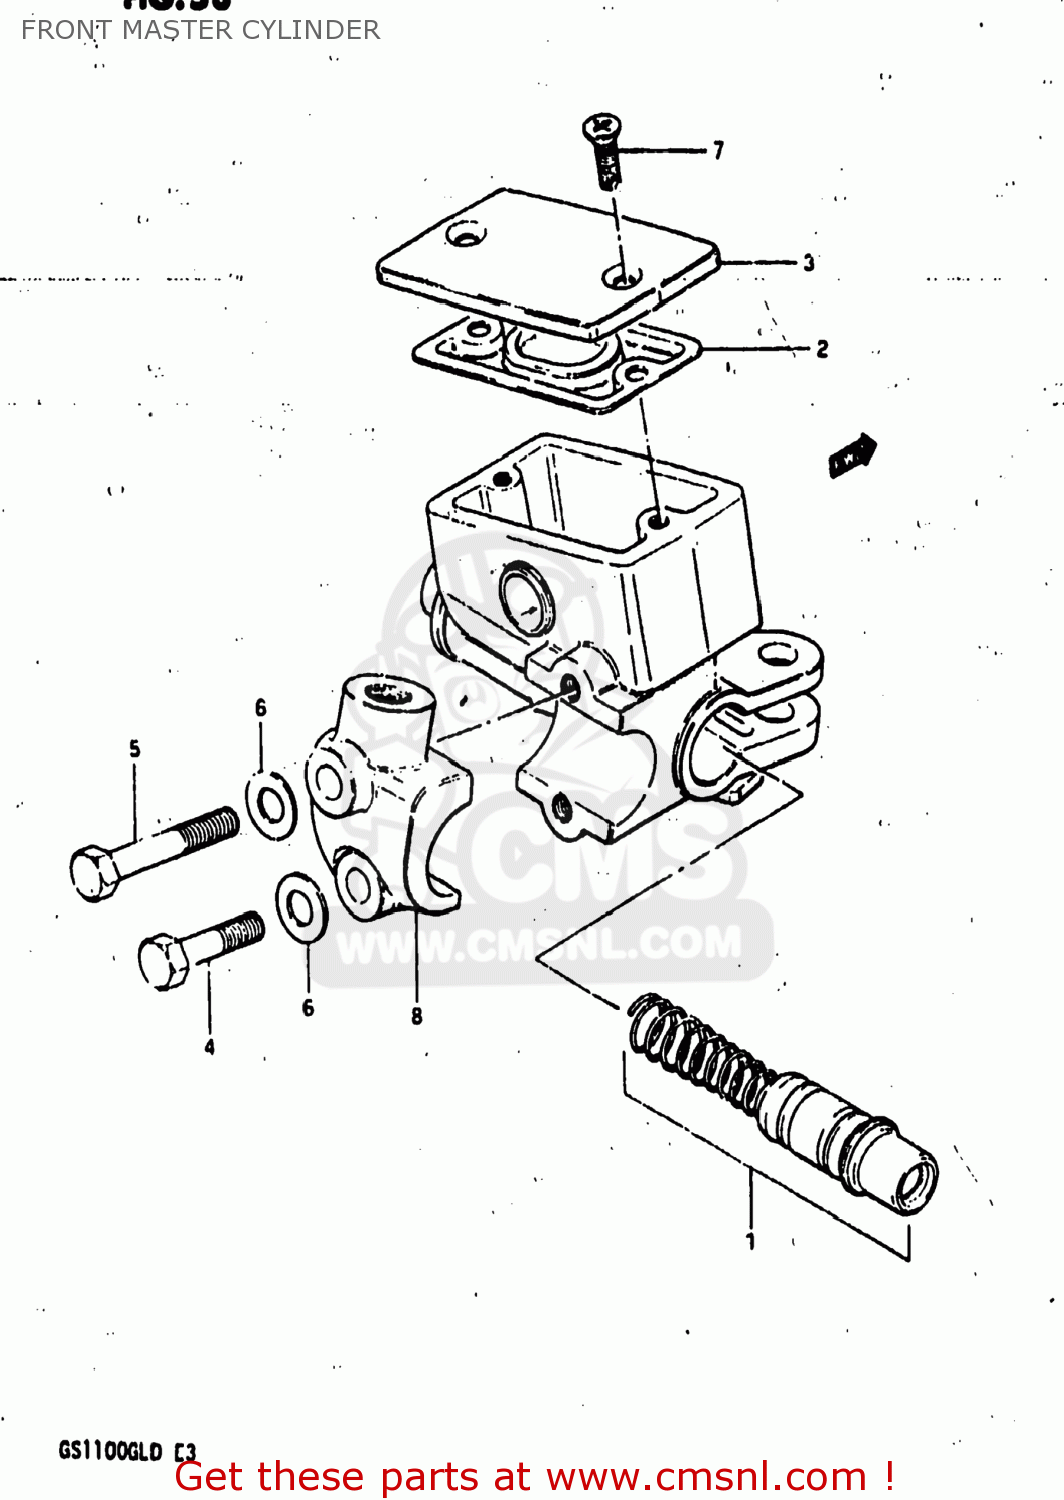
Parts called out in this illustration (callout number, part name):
1	PISTON & CUP SET
2	3
3	CAP
4	BOLT
5	BOLT 6X40
6	LOCK WASHER
7	SCREW
8	HOLDER
